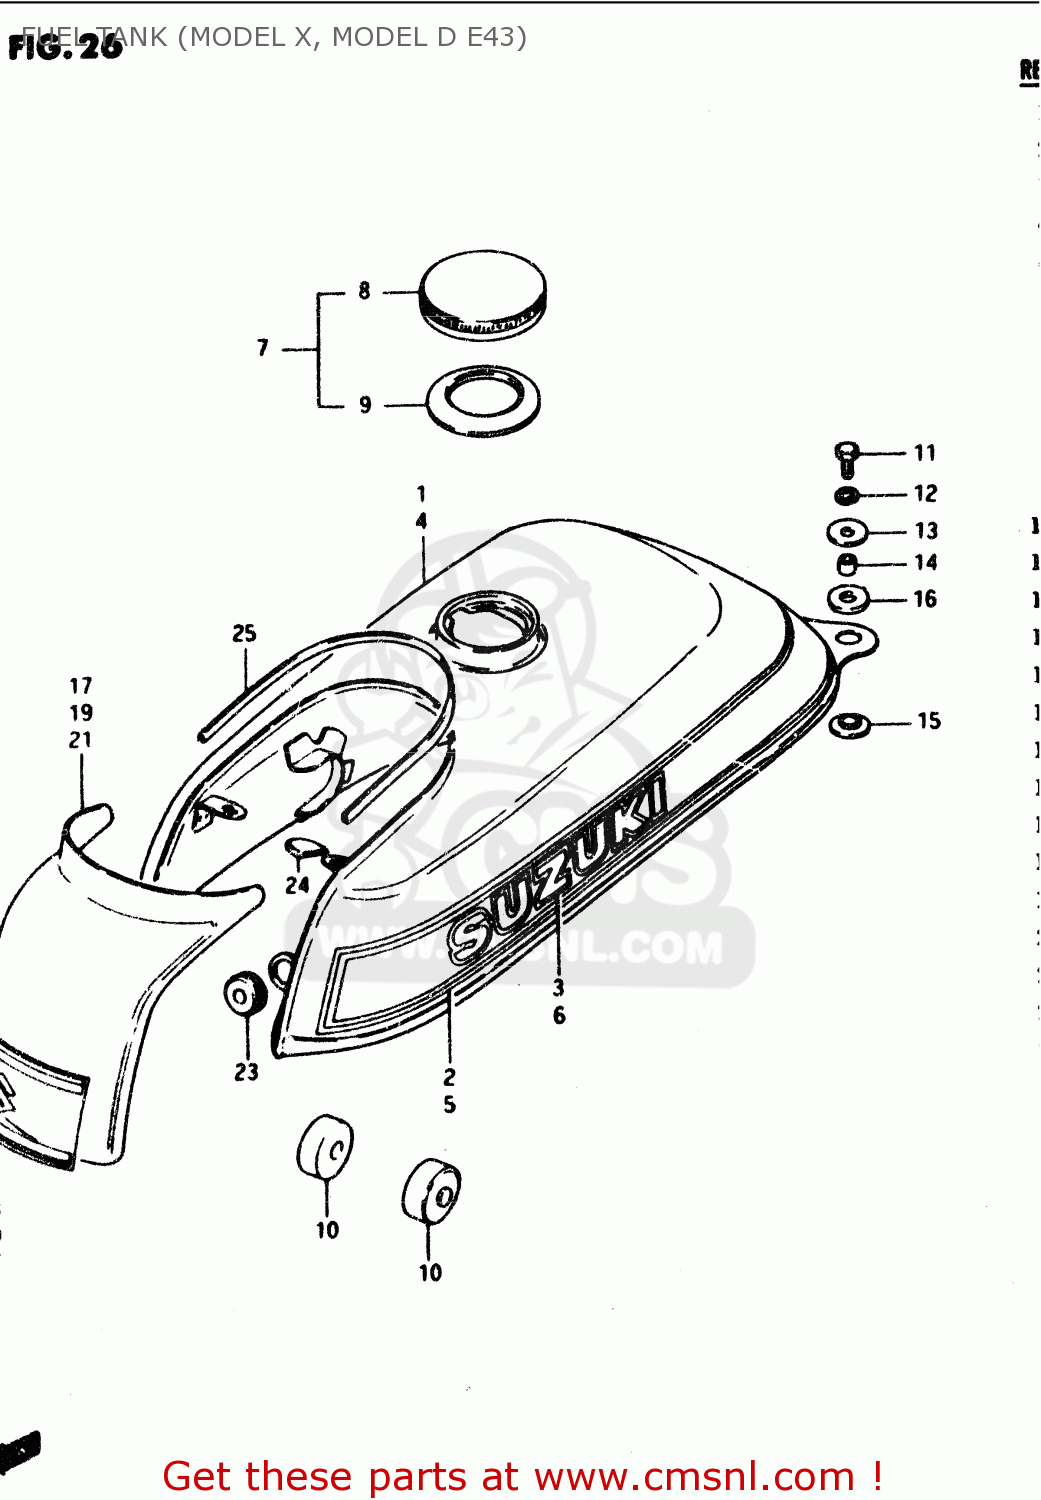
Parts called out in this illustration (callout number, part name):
1	TANK ASSY, FUEL (BLACK)
2	TAPE SET
3	EMBLEM (SILVER)
4	TANK ASSY, FUEL (RED)
5	TAPE SET
6	EMBLEM
7	CAP ASSY,FUEL TANK FILLER
8	CAP,FUEL TANK
9	GASKET (NAS)
10	CUSHION
11	BOLT
12	WASHER,LOCK
13	WASHER (6.5X24X1.6)
14	SPACER (6.8X10X10)
15	CUSHION
16	CUSHION
17	COVER,FUEL TANK FR
18	EMBLEM
19	COVER, FRONT (RED)
20	EMBLEM
21	COVER, FRONT (YELLOW)
22	EMBLEM
23	CUSHION
24	CUSHION
25	MOLDING
